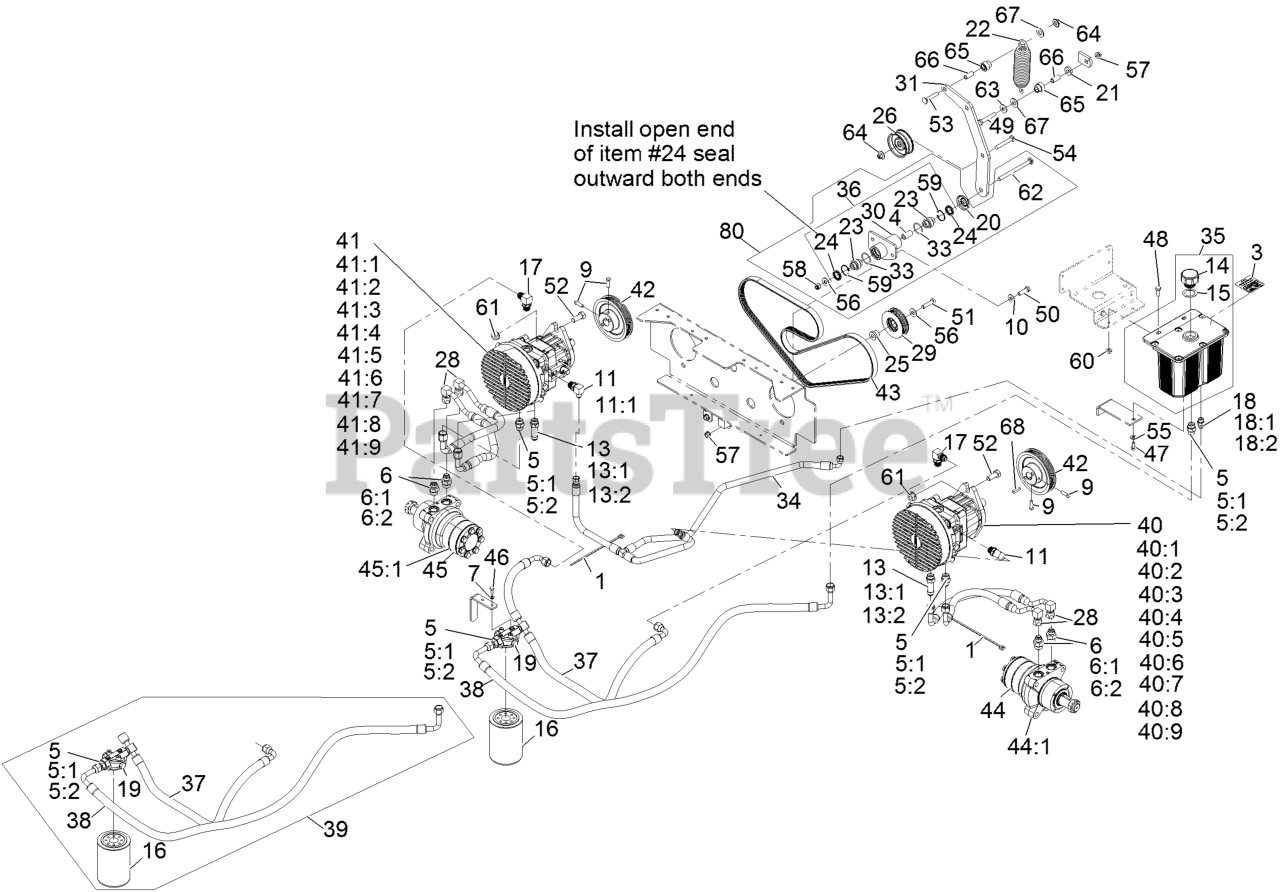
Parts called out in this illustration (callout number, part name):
1	TIE-PLASTIC
3	DECAL-HYDRAULIC TANK
5	FITTING-STRAIGHT
6	FITTING-STRAIGHT
7	WASHER-LOCK
9	SCREW-SET
10	WASHER-BELLEVILLE
11	FITTING-ELBOW, 90 DEG
13	ADAPTER-STR, LONG
14	Cap-Reservoir, HYD
15	GASKET-CAP
16	FILTER,XP HYD 25 MICRON
17	FITTING-90 DEG
18	FITTING-STRAIGHT
19	HEAD-FILTER
20	GUARD-TOP
21	SPACER-BRACKET, GUIDE
23	BEARING-SPHERICAL
24	SEAL-LIP, SINGLE
25	SPACER,LOWER FRAME IDLER
26	IDLER,FLANGED
28	HYD HOSE ASM
29	ASM,LOWER FRAME IDLER
31	ARM,PUMP IDLER
34	ASM,CASE DRAIN HOSE
36	Asm, Pump Idler
37	ASM, HOSE-PUMP INLET
38	ASM, HOSE-FILTER INLET
39	ASM, Filter HD. W/ Hoses
40	PUMP, LH
40:2	KIT, INPUT SHAFT
40:3	THRUST BEARING KIT
40:5	PLATE-VALVE
40:6	FAN-7",21CC PW PUMP
40:7	GUARD-FAN, PUMP
40:9	SHOCK VALVE KIT
41	PUMP, RH
41:2	KIT, INPUT SHAFT
41:3	THRUST BEARING KIT
41:5	PLATE-VALVE
41:6	FAN-7",21CC PW PUMP
41:7	GUARD-FAN, PUMP
41:9	SHOCK VALVE KIT
42	SHEAVE,5K 5.0" PD POLY-V
43	BELT, 5K 68.8
44	HYD MOTOR ASM (CCW)
45	HYD MOTOR ASM (CW)
46	SCREW-HH
47	SCREW-HH
48	Screw-HWH 5/16-18 X 3/4 Tf
49	SCREW-HH
50	SCREW-HH
51	SCREW-HH
52	SCREW-HH
53	SCREW-HH
54	SCREW-CARR
55	WASHER-PLAIN
56	WASHER-FLAT
57	NUT-HHF, WHIZ
58	NUT-LOCK, NI
59	RING-SNAP
61	NUT-HHF
62	BOLT CARR 3/8-16X5
63	WASHER
64	Nut-Nyloc 3/8-16 Flg
65	BUSHING,PLASTIC
67	WASHER-TEFLON
80	KIT,PUMP IDLER
